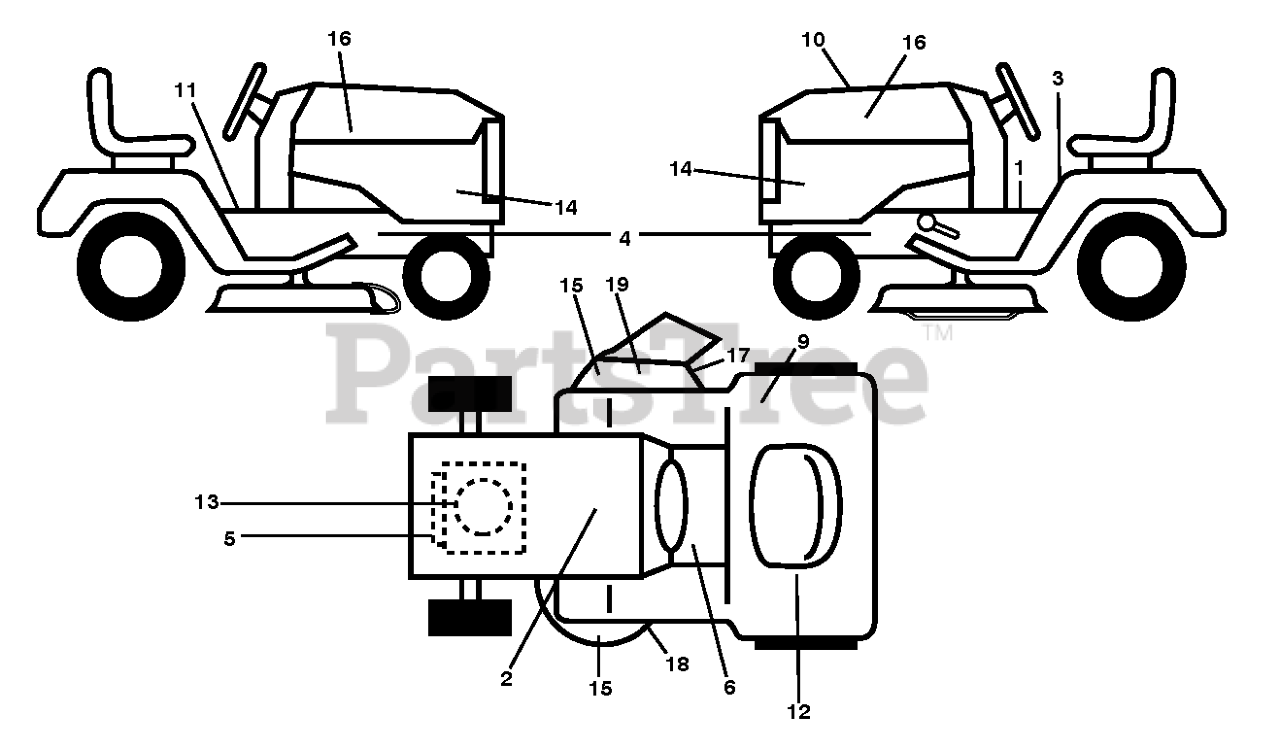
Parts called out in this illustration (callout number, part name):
1	DECAL.PARKING.BRAKE.SADDLE.LT
2	DECAL BTRY SYMBOLS
3	DECAL.READ.OWN.MAN.SYMBOL.LT
4	DECAL.CHASSIS.HOT.MUFFLER
5	DECAL.ENG.BS.20.ENDUR.382232
6	DECAL.FNDR.SDLE.BRAKE.CLUTCH.6
9	DECAL.FWD/REV.PEDAL.SYMBOL
10	DECAL.RPL.BSM40.42F.LT.K46
11	DECAL.FNDR.SDLE.BRAKE.CLUTCH.6
12	DECAL.RESERVEFUELSELCTR.ENG
13	DECAL.ENGINE.WARNING
14	DECAL.SDPNL.GT2.YTH2242TDRF
15	DECAL.DECK.6MIL.EURO.NOSTEP
16	DECAL.BADGE.170MM.TEXTLOGO.
17	DECAL.DECK.6MIL./DEF.SHLD.WARN
18	DECAL.MOWER.SCH.48/54.PREM
19	DECAL, DECK DEFLECTOR, WARNING
